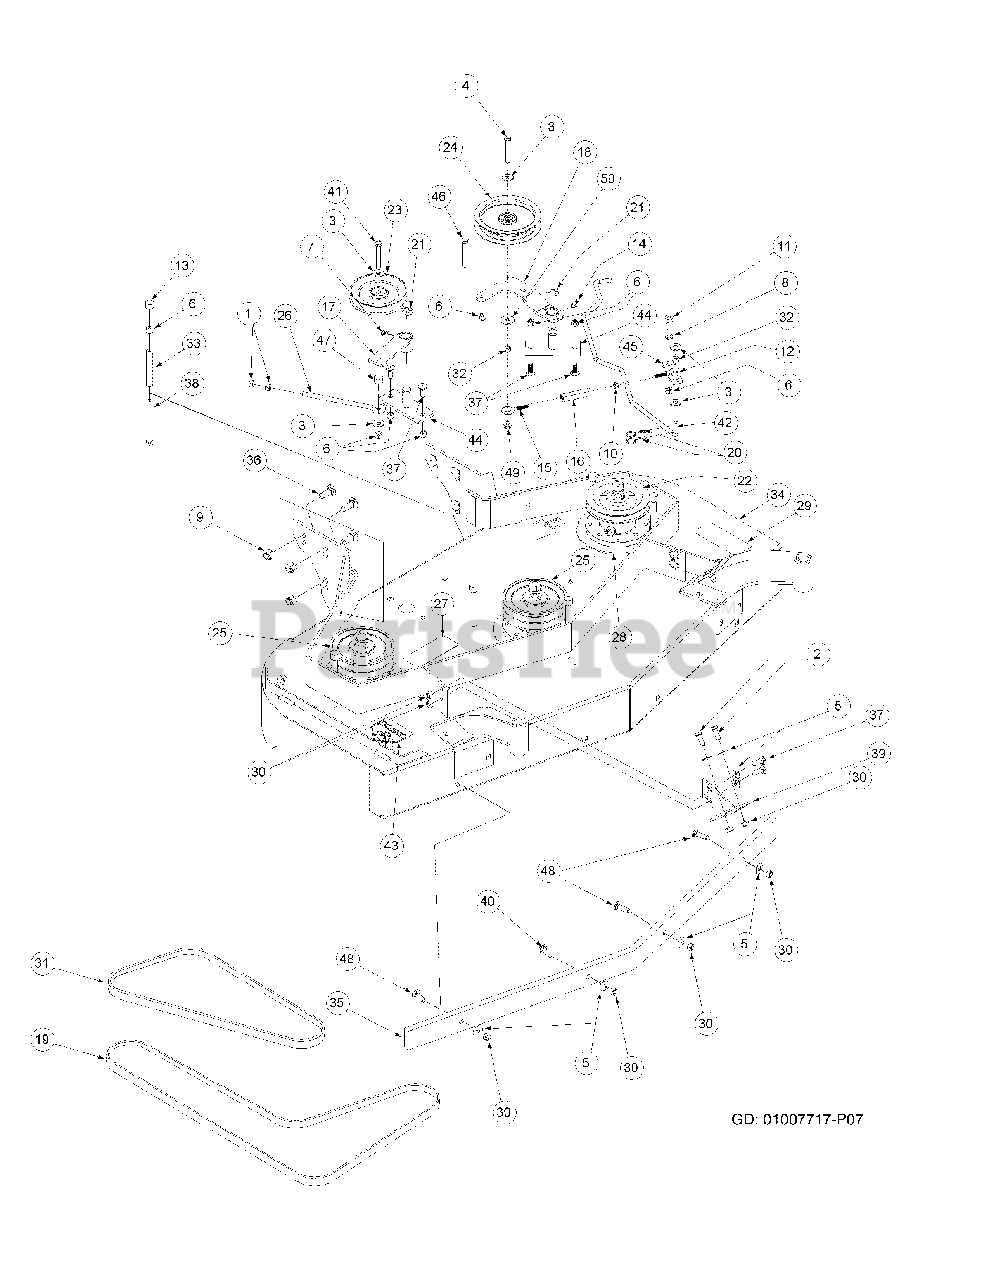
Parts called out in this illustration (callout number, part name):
1	Hex Nut, 3/8-16
2	Hex Cap Screw, 3/8-16, 1
3	Flat Washer, 3/8 Zinc
4	Washer, 1.25 x .411 x .100
5	Flat Washer, 3/8 Zinc
6	Lock Nut, Nylon Insert, 3/8-16
7	Grease Fitting, 1/4-28, 90°
8	Shim Washer
9	Nut, Flange Lock, 1/2-13
10	Hex Nut, 5/16-18
11	Shoulder Bolt
12	Eye Bolt, Right Hand
13	Vinyl Cap
14	Grease Fitting, 45°, 1/4-28
15	Eye Bolt, Left Hand
16	Turnbuckle
17	Idler Arm "B"
18	Idler Arm "A"
19	Drive Belt
20	Hair Pin, 3/8"-1/2"
22	Deck Pulley
23	Idler Pulley
24	Idler Deck Take-up
25	Double Pulley
26	Rod Belt Tensioner
27	Decal Rotating Blade
28	Spindle Backing Plate
29	Decal Warning Shield Missing
30	Lock Nut, Metal, 3/8-16
31	Drive Belt
32	Sleve Turnbuckle
33	Spacer Belt Guide
34	Deck Weldment Mower
36	Carriage Bolt, 1/2-13 x 1-1/4
37	Carriage Bolt, 3/8-16 x 1
38	Carriage Bolt, 3/8-16 x 4-1/2
39	Caster Support Assembly
40	Carriage Screw, 3/8-16 x 1-1/2
41	Hex Cap Screw, 3/8-16, 2.25
42	Rod Clutch Link
43	Decal, Danger Hands and Feet
44	Idler Base
46	Hex Cap Screw, 3/8-16, 2.75
47	Sleeve Tensioner
48	Carriage Screw, 3/8-16 x 1-1/4
49	Hex Nut Flange Lock, 3/8-16
